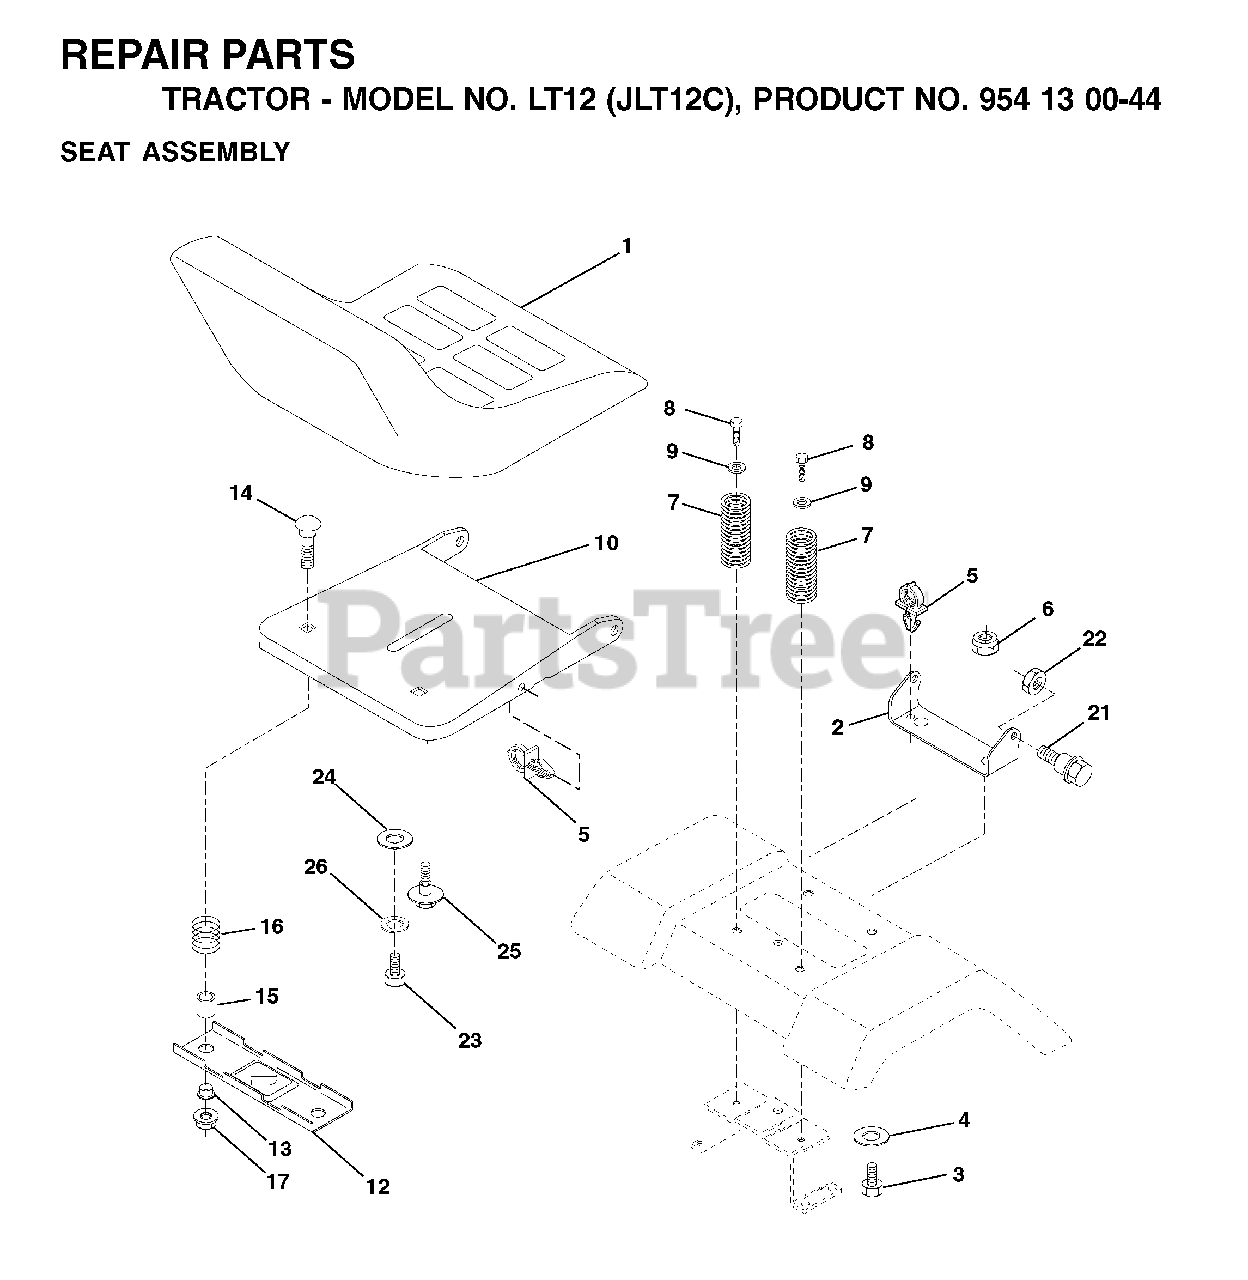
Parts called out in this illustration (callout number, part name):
1	SEAT
2	SEAT PIVOT BRKT
4	WASHER PM
5	PUSH CLIP
6	NUT
7	SPRING COMPRESSION
8	SCREW 3/8-16X1
9	WASHER
10	PAN, SEAT
12	BRKT SWITCH
14	BOLT.ROUND.HEAD.SQUARE.NECK
15	SPACER SPLIT 28X.96
17	NUT T
21	BOLT.SHOULDER.5/16-18
22	NUT.71038.31-18.HEX.NYLOCK
23	BOLT.HEX.BLACK
25	BOLT,SHOULD
26	LOCKWASHER
